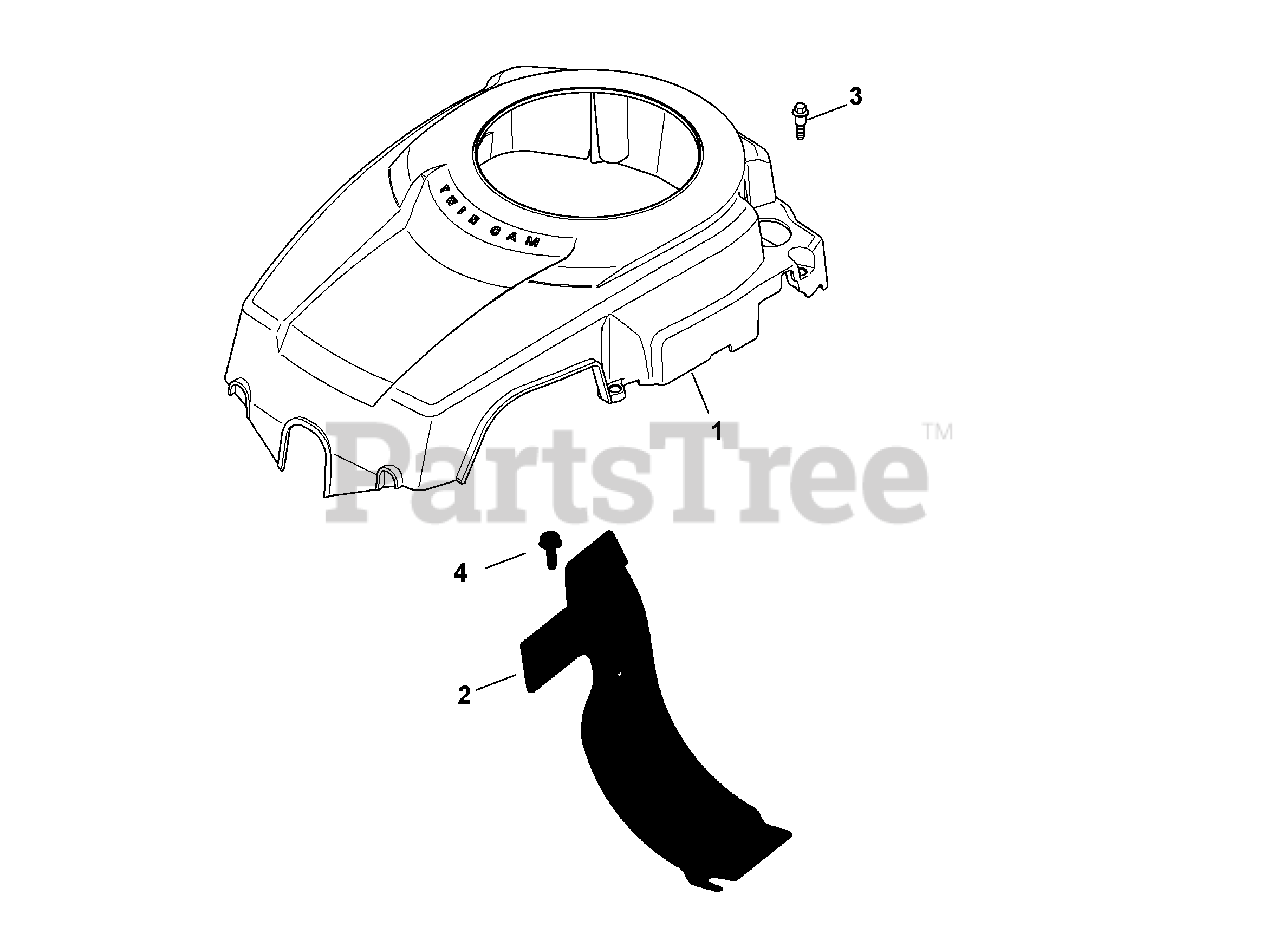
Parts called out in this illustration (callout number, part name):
1	Blower Housing Kit
2	Barrel Baffle
3	Shd. Thd. Frm. Screw, M6 X 1 X 26
4	Flg. Thd. Frm. Screw, M6 X 1.0 X 16
